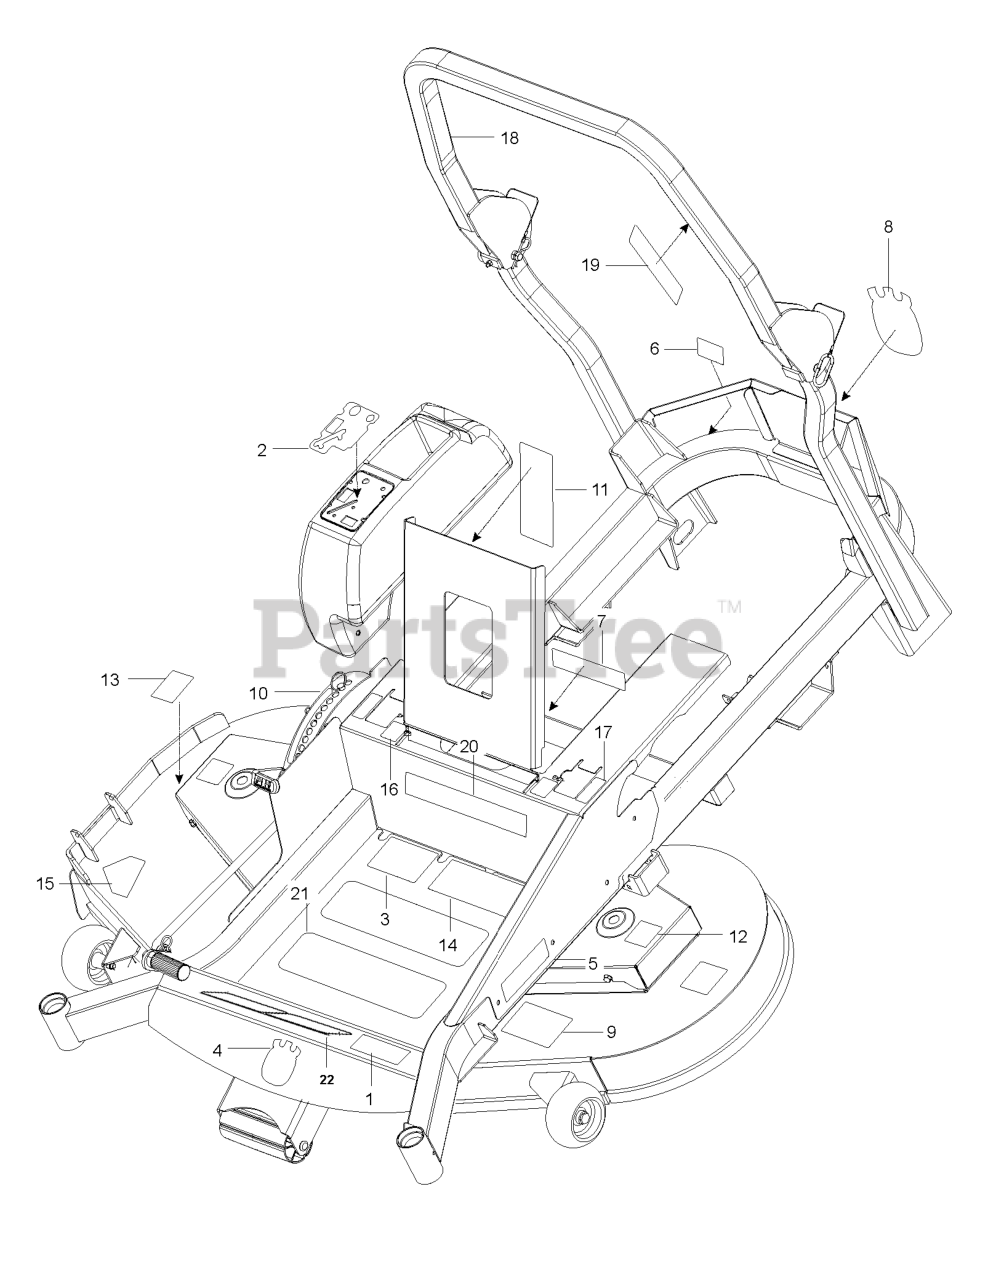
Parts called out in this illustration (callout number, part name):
1	DECAL.ZTR.MZ61.HUSQ
2	DECAL, CONSOLE HUS
3	DECAL.ZTR.STRTNGINST.REMOTECHK
3	DECAL, WARNING
4	DECAL.AUGER.HUSQ.CROWN.SNOW
5	RP.DECAL.BADGE.170MM.TEXTLOGO
6	DECAL, BELT DRIVE
7	EURO DECAL-BATTERY WARNIN6
8	DECAL, CROWN H, 110MM
9	DECAL, BELT ROUTING
10	DECAL, HEIGHT ADJUST
11	DECAL, SERVICE
12	DECAL.DECK.6MIL.EURO.NOSTEP
13	DECAL.DECK.6MIL./DEF.SHLD.WARN
14	DECAL ZTR WARNING DECAL DECAL.
15	DECAL, DECK DEFLECTOR, WARNING
15	DECAL, CPSC
16	DECAL.STR.S.T.SYSMBOLONLY.2014
17	DECAL, MOTION CONTROL
17	DECAL.ZTR.MOTCONTRL.SYMBOL.HUS
18	DECAL.ROP.Z400/400X.MZ/MZT/RZ
18	DECAL, ROPS, WARNING
19	DECAL ROPS
20	DECAL ZTR BRAND GRAPHIC DECAL.
21	ANTI-SKID PAD
22	DECAL.ZTR.MZ61.HUSQ
